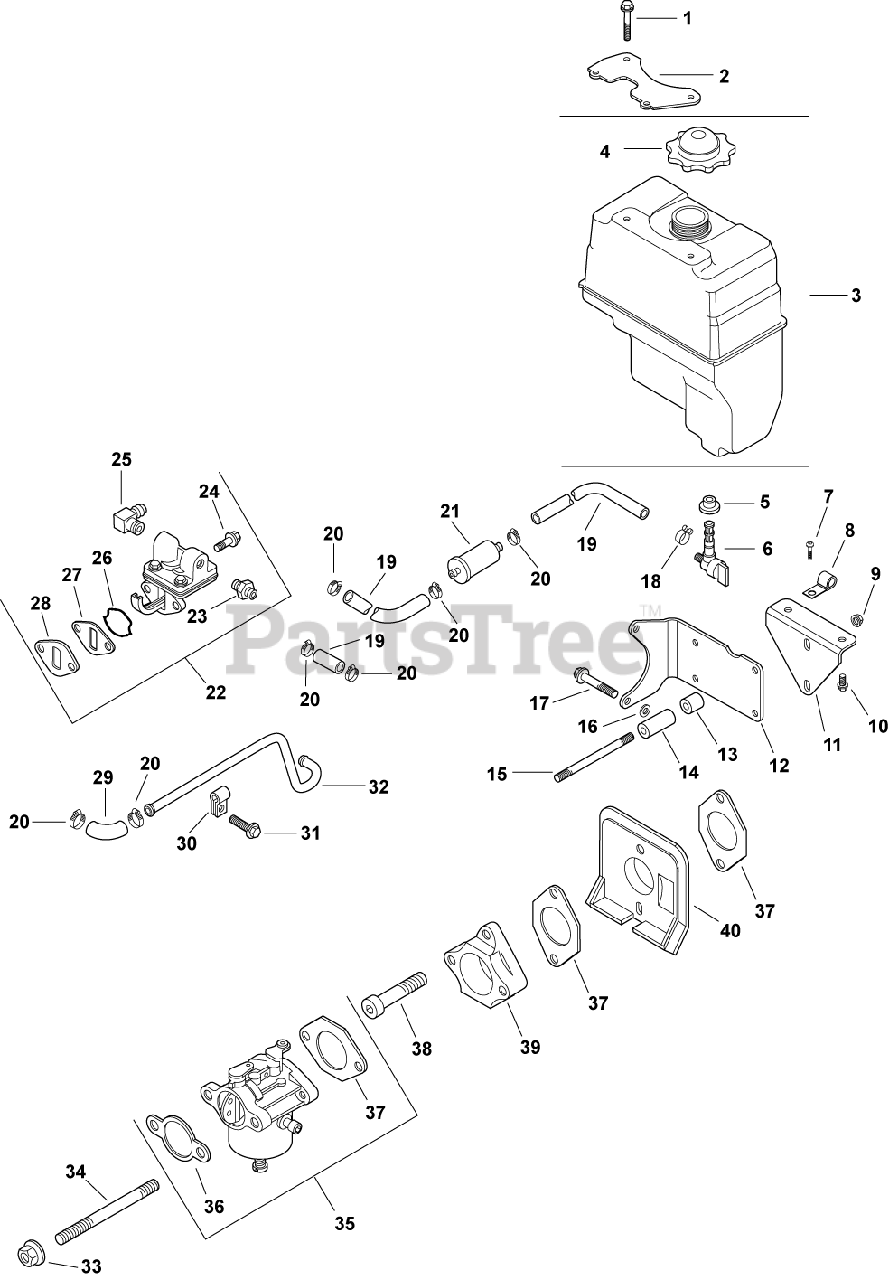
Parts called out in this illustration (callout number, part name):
1	SCREW,FLG THD FRM M6X1.0X25-(#25086395S)
2	BRACKET, FUEL TANK
3	KIT, FUEL TANK
4	CAP, FUEL TANK
5	BUSHING, FUEL TANK
6	VALVE, FUEL SHUT-OFF
7	SCREW, LBD SKT M6x1.0x20-(#25086403S)
8	CLIP, CABLE
9	NUT, FLG M8X1.25
10	SCREW, FLG M6X1.0X12
12	BRACKET, FUEL TANK
14	SPACER, FUEL TANK
15	STUD, M8X1.25X133-USE 25 755 54-S
16	WASHER, FLAT 11/32"
17	SCREW, FLG M8X1.25X50
18	CLAMP, BAND SPRING HOSE-(#2523737S)
19	HOSE,LW PERM.FUEL 24.00"-USE 25 111 81-S
20	CLAMP, HOSE (KM)-USE 25 237 31-S
21	FILTER,FUEL 51 MICRON (FUEL PUMP)
22	KIT, FUEL PUMP
23	KIT, STRAIGHT FITTING
24	SCREW,FLG THD FRM M6X1.0X20-(#25086396S)
25	CONNECTOR, 90 DEG. HOSE
26	O-RING, FUEL PUMP
27	SPACER, FUEL PUMP
28	GASKET, FUEL PUMP
29	HOSE, FUEL LOW-PERMEATION
30	CLIP, TUBE & WIRING (KM)
31	SCREW, FLG THD FRM M5X.8X10
32	LINE, FUEL - DISCONTINUED
33	NUT, FLG M6X1.0
34	STUD,M6X1.0X116
35	KIT, CARBURETOR
36	GASKET, CARBURETOR
37	GASKET, CARBURETOR
38	SCREW, SKT CAP M6X1.0X35
39	ADAPTER, CARBURETOR
40	DEFLECTOR, HEAT
